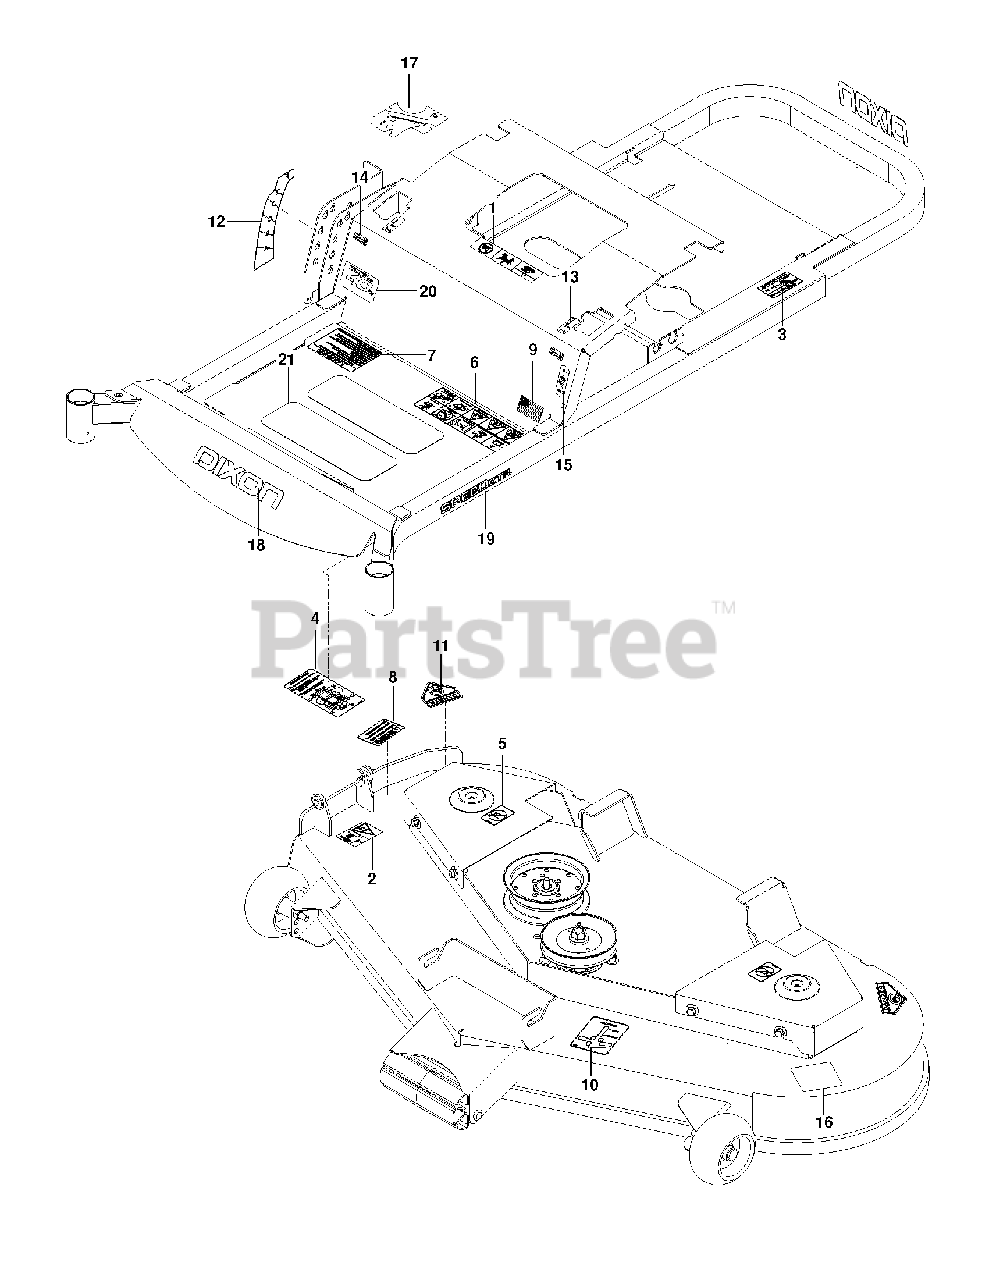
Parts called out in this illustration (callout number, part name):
2	DECAL, EURO SEVERING
3	DECAL, DO NOT MOUNT
4	DECAL, SERVICE
5	DECAL, NO STEP
6	DECAL, SAFETY WARNING
7	DECAL, WARNING
8	DECAL, DANGER
9	DECAL, FLAG
10	DECAL, BELT ROUTING
11	DECAL, CPSC
21	ANTI-SKID PAD
